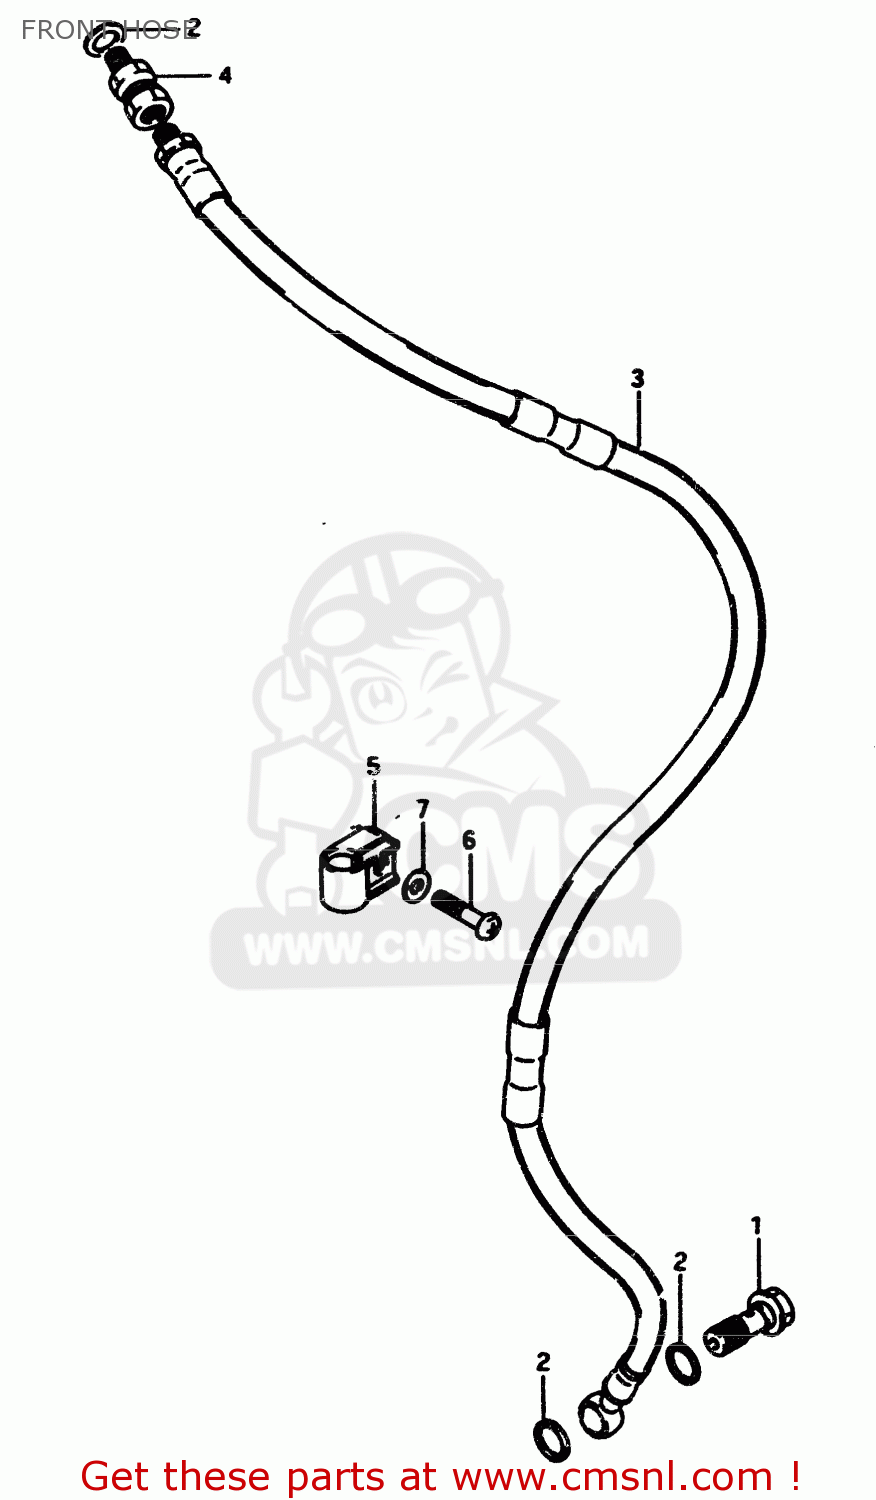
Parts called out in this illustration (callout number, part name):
1	BOLT UNION
2	WASHER(10X15X1.5)
3	HOSE,FRONT BRAKE
4	ADAPTER,BRAKE HOSE
5	CLAMP,FRONT BRAKE HOSE
6	SCREW
7	WASHER
